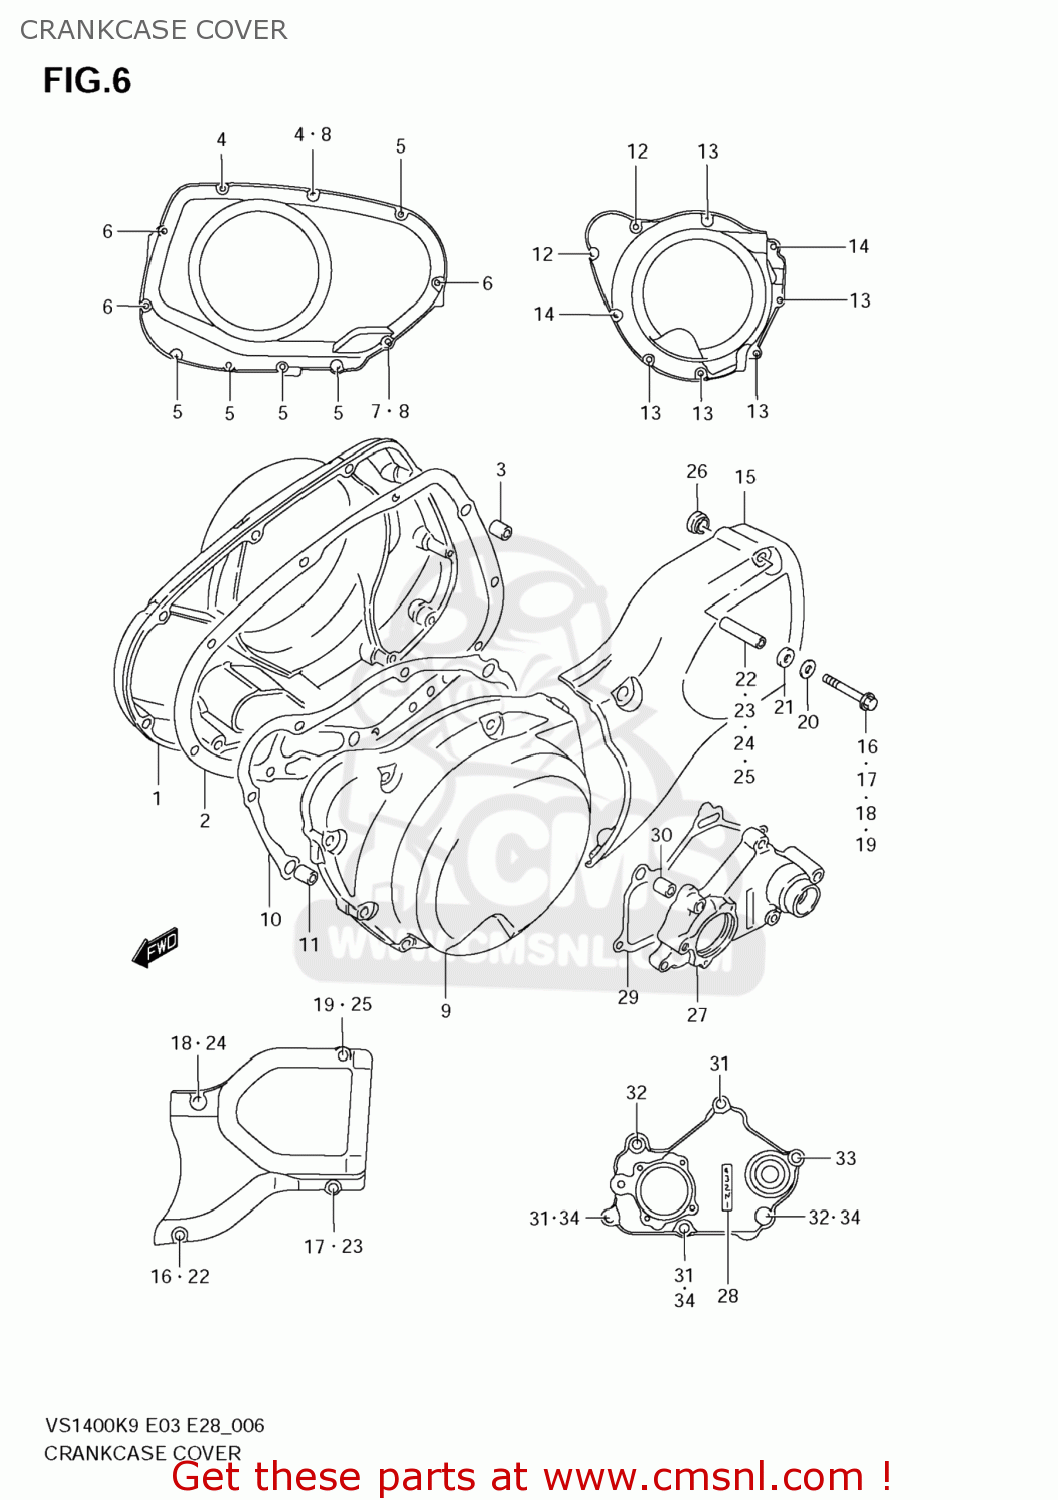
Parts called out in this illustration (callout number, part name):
1	COVER,CLUTCH
2	GASKET,CLUTCH COVER (NAS)
3	PIN
4	BOLT(6X30)
5	BOLT(6X30)
6	BOLT(6X40)
7	BOLT(6X55)
8	GASKET(5.8X13X1.2) (NAS)
9	COVER,GENERATOR
10	GASKET,GENERATOR COVER (NAS)
11	PIN(8.4X11X20)
12	BOLT(6X30)
13	BOLT(6X35)
14	BOLT(6X45)
15	COVER,SECONDARY GEAR CASE
16	BOLT(6X35)
17	BOLT(6X40)
18	BOLT(6X60)
19	BOLT(6X60)
20	WASHER(6.5X14X1.6)
21	WASHER(8.7X16X5)
22	SPACER(6.5X9X21)
23	SPACER(6.5X9X26)
24	SPACER(6.5X9X49)
25	SPACER(6.5X9X45.9)
26	WASHER(8.7X16X5)
27	COVER,GEAR SHIFT
28	LABEL,GEAR SHIFT
29	GASKET,GEAR SHIFT COVER (NAS)
30	PIN
31	BOLT(6X25)
32	BOLT(6X35)
33	BOLT(6X45)
34	GASKET(5.8X13X1.2) (NAS)
